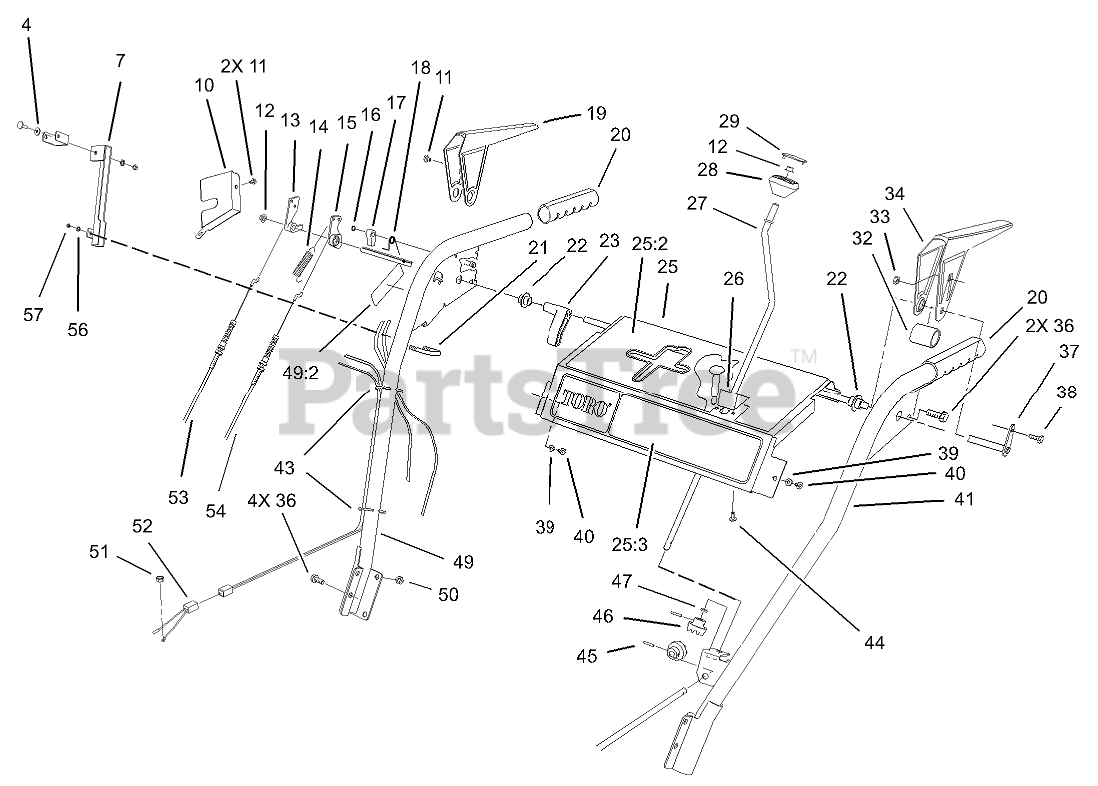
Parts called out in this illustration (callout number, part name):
4	WASHER-FLAT
7	LIGHT MOUNT ASM
10	COVER-LOCK, LEVER
11	SCREW-HH
12	RETAINER-PUSH ON
13	TANG-LOCKING
14	SPRING-EXTENSION
15	CAM-RELEASE
16	E-RING-RETAINER
17	LATCH-LOCKING
18	SPRING-TORSION
19	LEVER-TRACTION, RH
20	GRIP-HANDLE
21	U-BOLT
22	BUSHING-LEVER
23	LEVER-TRIP
25	CONTROL PANEL ASM
25:2	DECAL-CONTROL
25:3	DECAL - FRONT PANEL
26	PLATE-GUIDE
27	CRANK-ROD, CHUTE
28	KNOB-CONTROL, CHUTE
29	COVER-KNOB
32	SPACER-LEVER, TRACTION
33	NUT-LOCK, NI
34	LEVER-TRACTION, LH
36	SCREW-HWHTF
37	CROSS ROD ASM
38	SCREW-HWH
39	WASHER-FLAT
40	SCREW-HWHTF
41	LH HANDLE ASM
43	TIE-CABLE
44	SCREW
45	PIN-SPRING
46	GEAR-UNIVERSAL
47	WASHER-RUBBER
49	HANDLE ASM
49:2	DECAL-ADJUSTMENT
50	NUT-LOCK, NI
51	NUT-HEX
52	WIRE ASM
53	CABLE-IMPELLER
54	CABLE-TRACTION
56	WASHER-PLAIN
57	NUT-LOCK, NI
